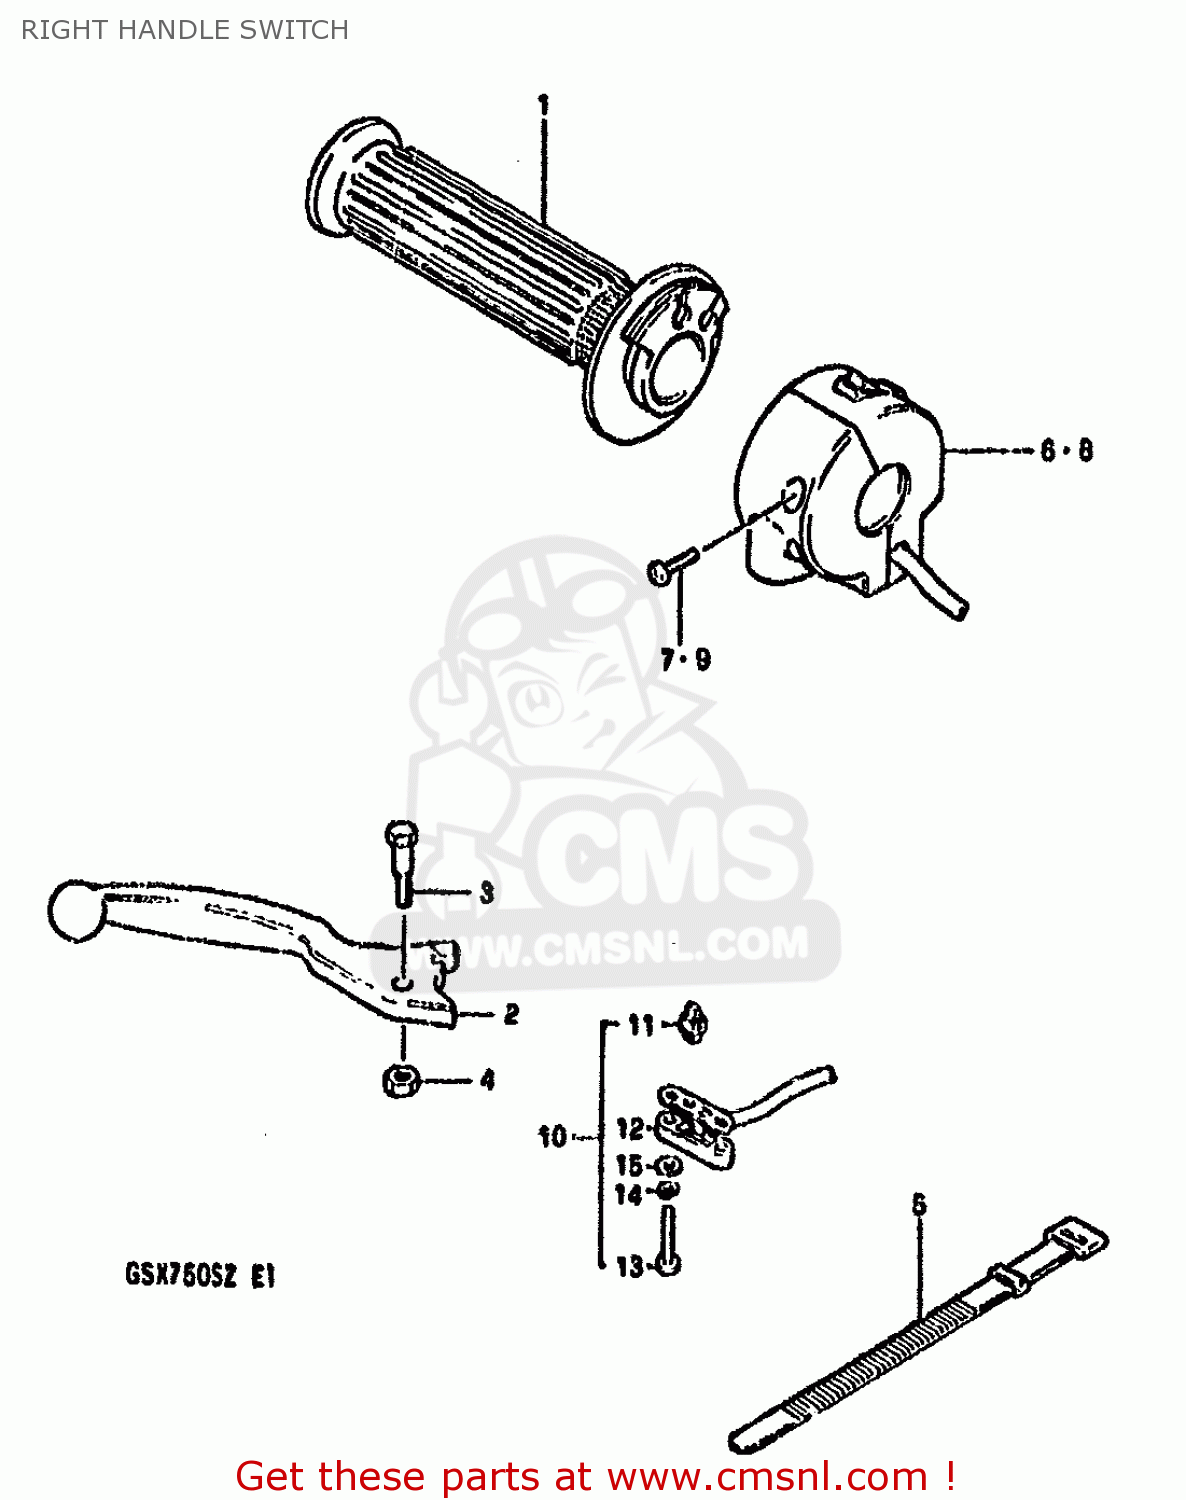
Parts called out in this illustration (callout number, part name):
1	GRIP,THROTTLE
2	LEVER,BRAKE
3	BOLT
4	NUT 6MM
5	CLAMP(L:120)
6	SWITCH ASSY, HANDLE RH
7	SCREW
8	SWITCH ASSY, HARDLE RH
9	SCREW
10	SWITCH ASSEMBLY
11	CONTACT,SWITCH
12	COVER,FR BK TERMINAL BASE
13	SCREW
14	LOCK WASHER
15	WASHER
